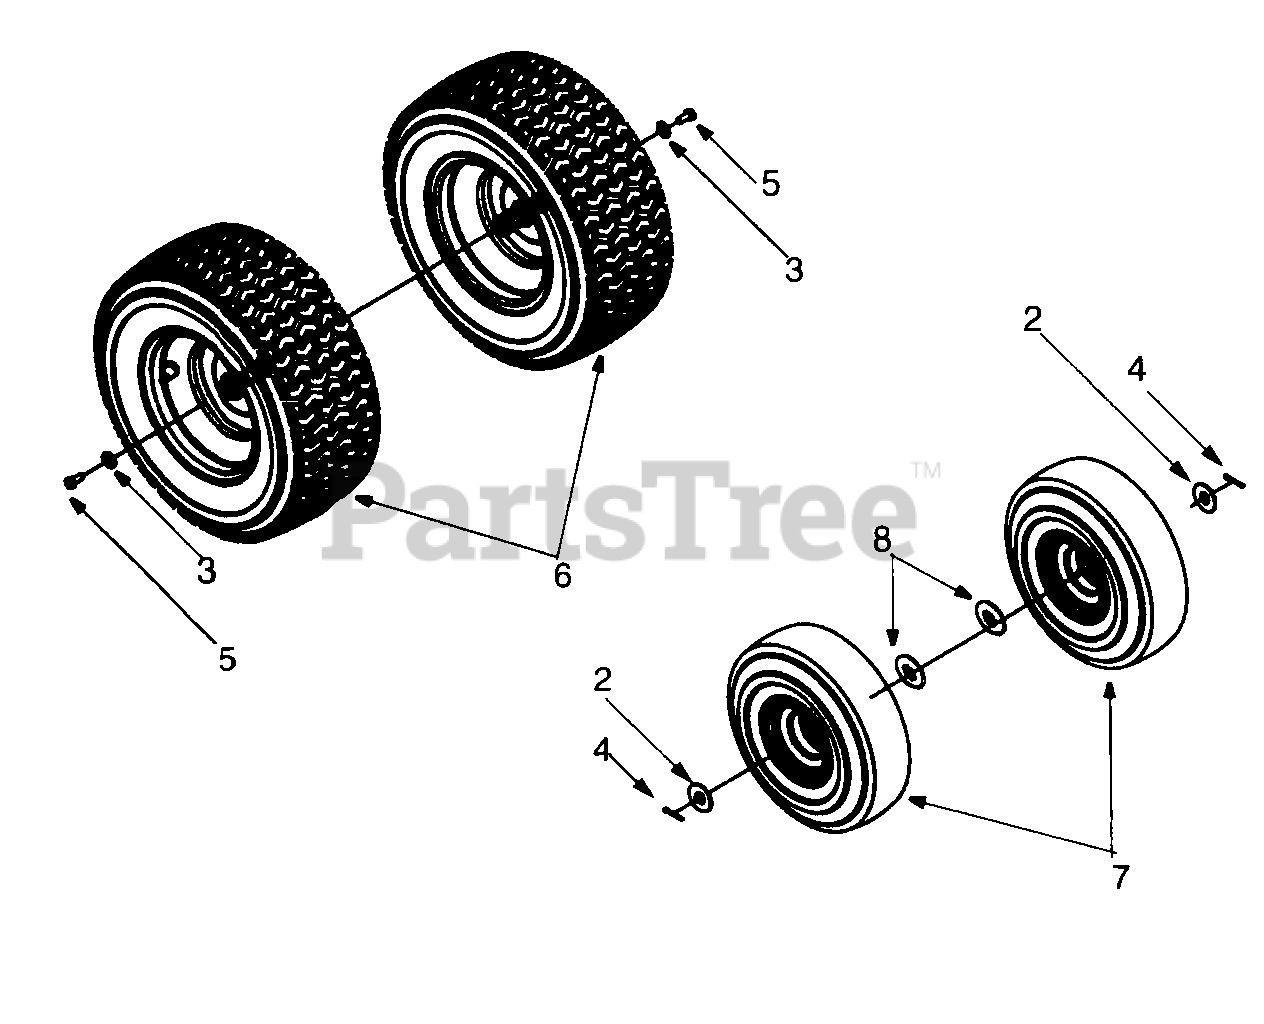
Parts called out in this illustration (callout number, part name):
2	Flat Washer .635 x 1.589 x .060
3	Bell Washer.345 I.D. x.88 O.D. x .06
4	Hairpin Clip
5	Hex Screw 5/16-24 x .75
